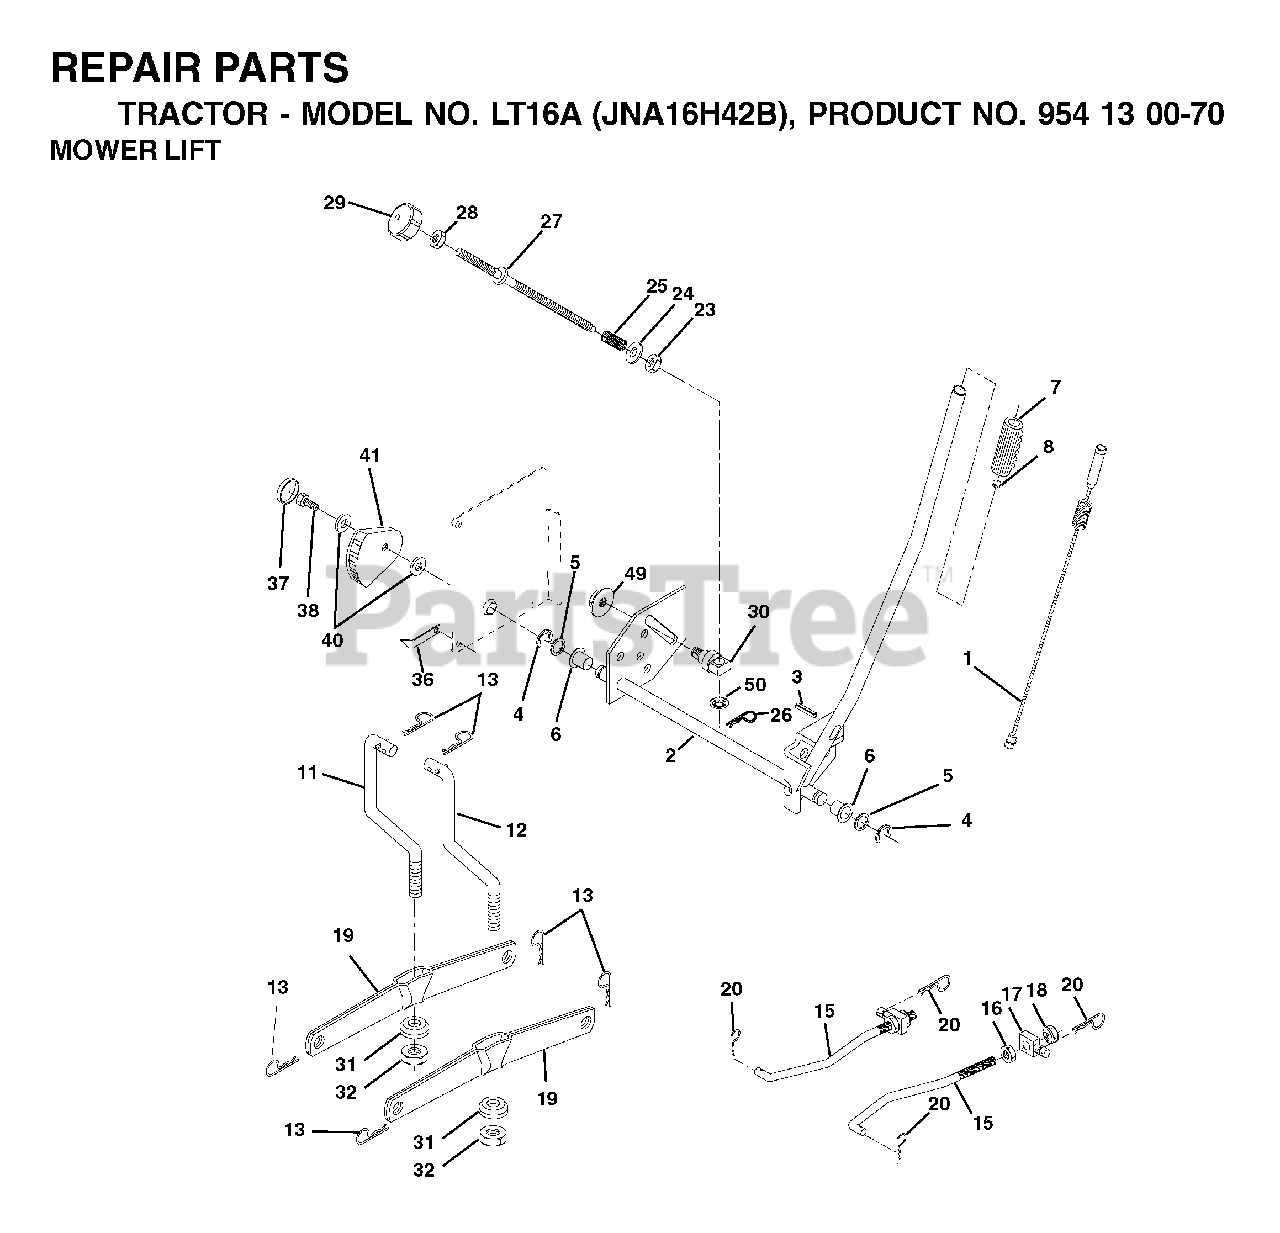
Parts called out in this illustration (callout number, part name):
1	WIRE ASM INNER W/ PLUNGER LT
2	SHAFT ASM R HANDLE
3	PIN GROOVE
4	RETAINING RING LT
6	BEARING.NYLON
7	GRIP HANDLE
8	PLUNGER BUT KIT
11	LINK LIFT LH
12	LINK LIFT RH
13	RETAINER-SPRNG RB
15	LINK.SUSPENSION.FRONT
16	NUT
18	NUT
19	ARM.REAR.SUSPENSION
20	SPRING RETAINER
25	SPRING**
26	RETAINER CLIP
27	ROD ADJ LIFT
28	NUT
29	KNOB INF 3/8-16
31	BEARING.PIVOT.LIFT
32	NUT CROWNLOCK 3/8-24
36	POINTER, HEIGHT INDICATOR
37	PLUG,HOLE
38	SCREW 5/16-18X1
41	IND. HEIGHT STLT
49	NUT
50	NUT PUSH M
